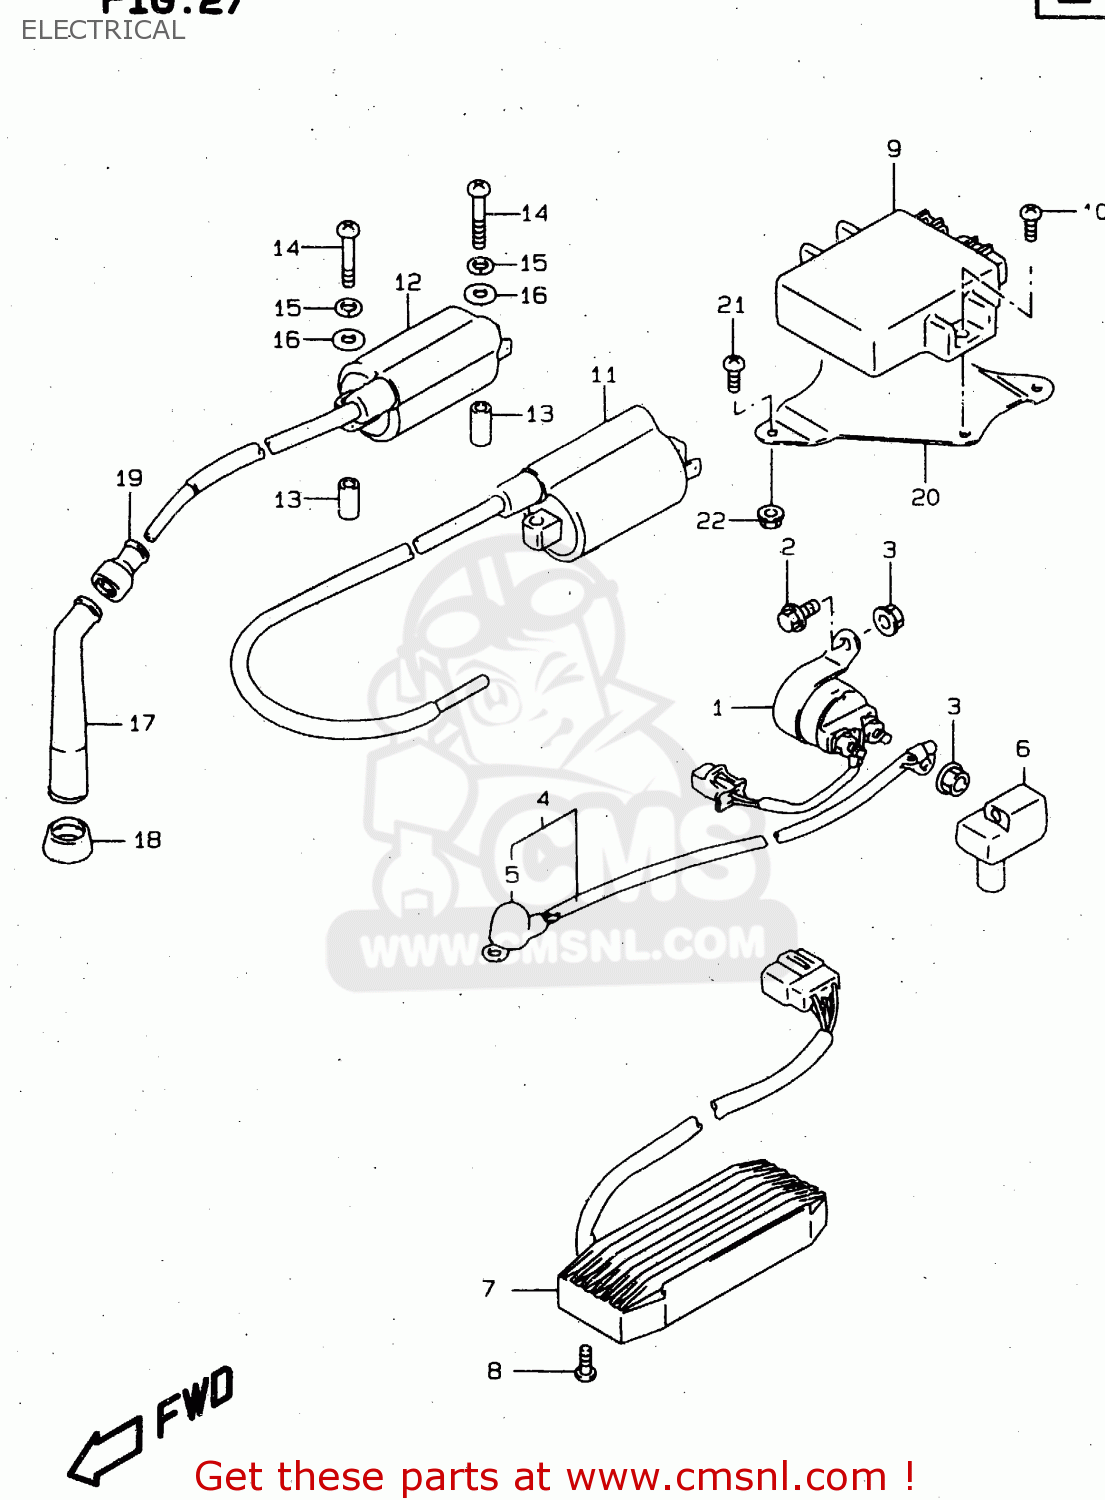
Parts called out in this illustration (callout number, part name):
1	RELAY ASSY,STARTING MOTOR
2	BOLT
3	NUT
4	WIRE,STARTER MOTOR LEAD
5	CAP,STARTER MOTOR LEAD
6	CAP,STARTER RELAY
7	RECTIFIER ASSY
8	BOLT
9	IGNITOR ASSY
10	SCREW 6X12
11	COIL ASSY,IGNITION
12	COIL ASSY,IGNITION
13	SPACER(6.4X10X19)
14	SCREW (5X38)
15	LOCK,WASHER
16	WASHER
17	CAP,SPARK PLUG
18	SEAL,SPARK PLUG CAP
19	SEAL,HIGH TENSION CORD
20	PLATE,IGNITOR FITING
21	BOLT
22	NUT
